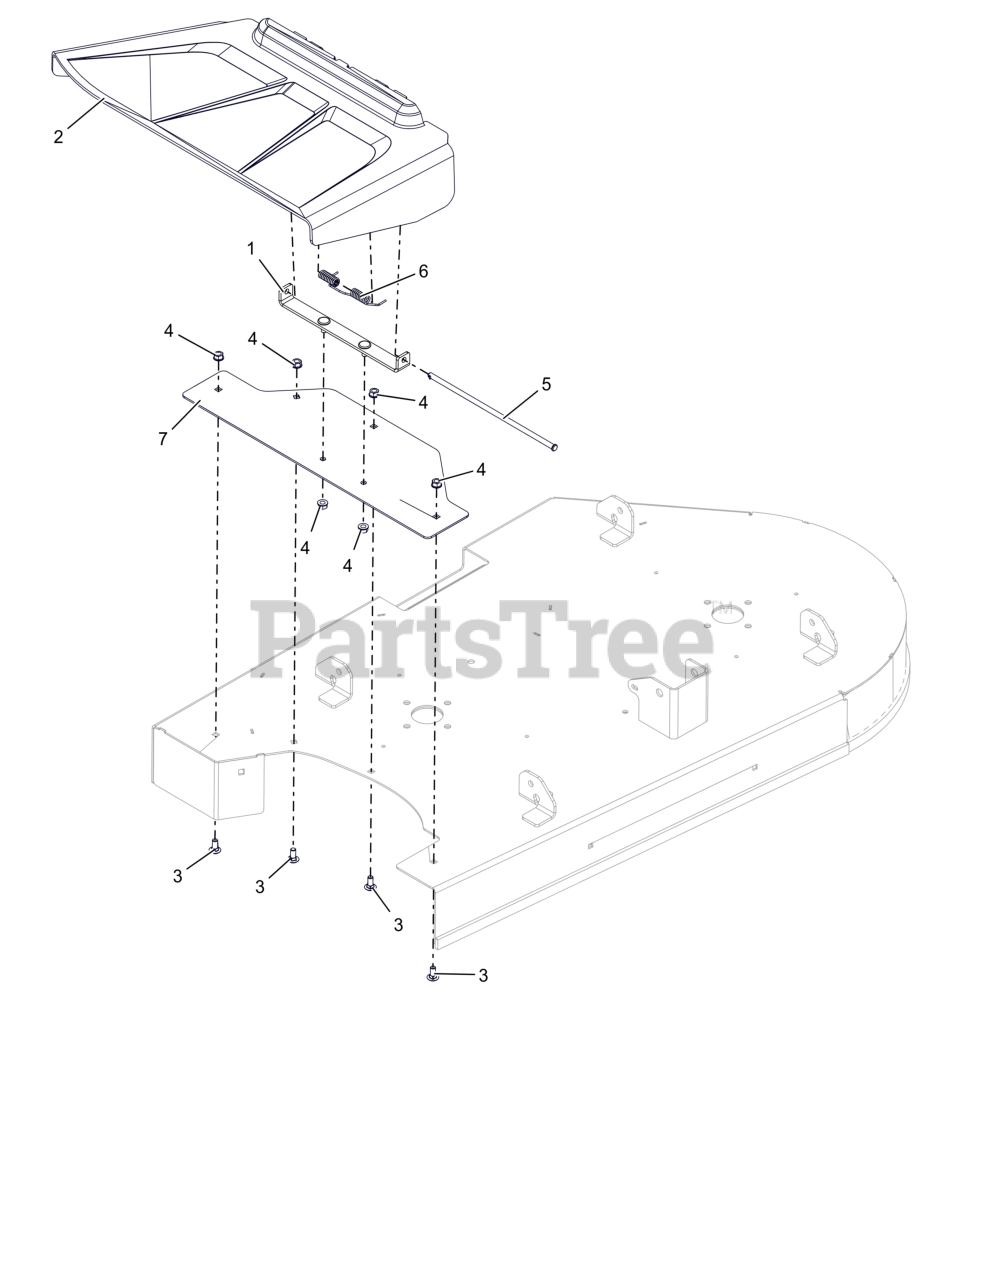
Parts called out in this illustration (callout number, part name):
2	CHUTE, SIDE DISCHARGE
3	BLT,RHSN .31-18X.75 G5 ZCC
4	NUT,LK-CTR-FLG .31-18 GF ZCC
5	PIN, SLIC-.312X10.45
6	SPRING-TORSION
7	PLATE, DECK - DISCHARGE (RED)
